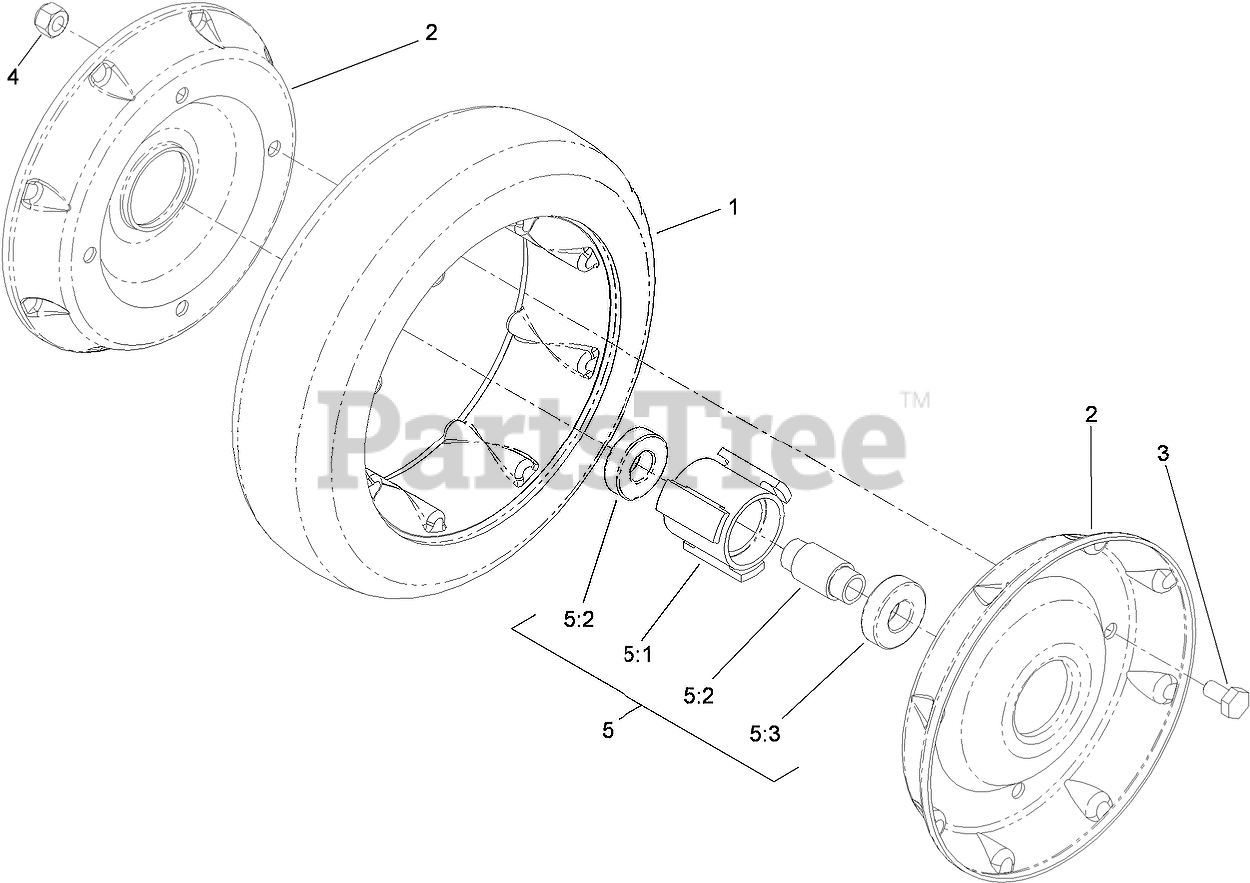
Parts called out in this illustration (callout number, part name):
2	PLATE-WHEEL, HALF
3	SCREW-HH
4	NUT-LOCK, NI
5	Hub and Bearing ASM
5:1	HUB-BEARING
5:2	SPACER-BEARING
5:3	BEARING-WHEEL
